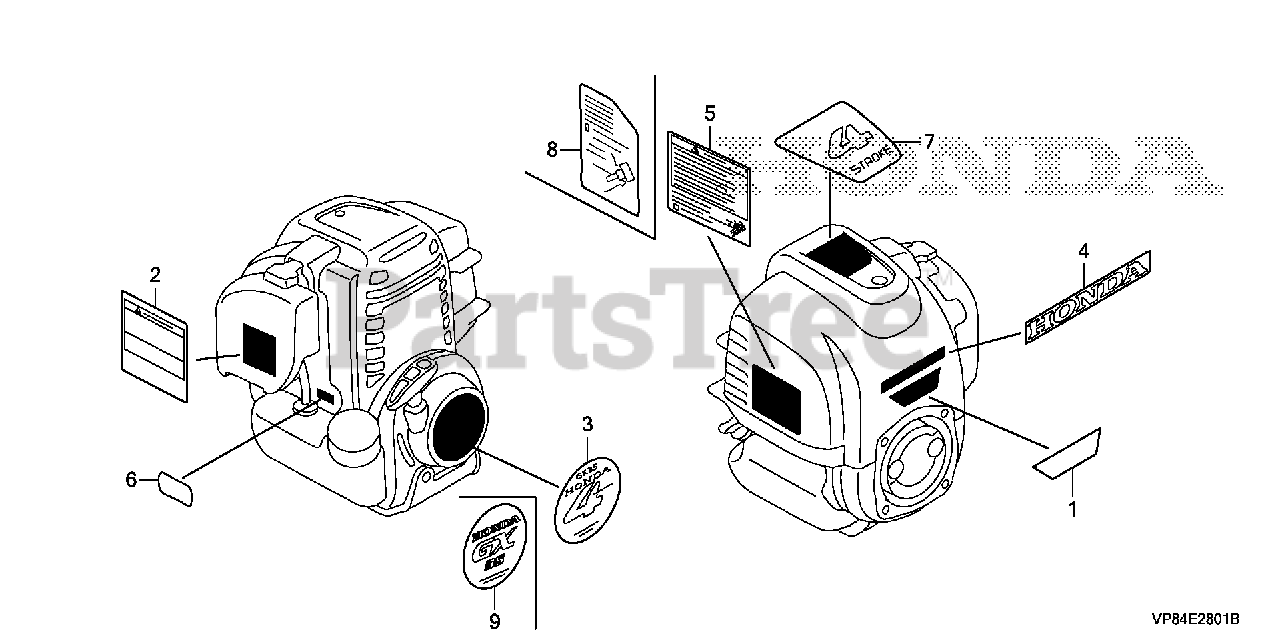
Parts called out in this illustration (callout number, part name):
1	MARK, EMBLEM (UMC435)
5	LABEL, SPARK WARNING
7	MARK (4-STROKE)
9	MARK, EMBLEM
